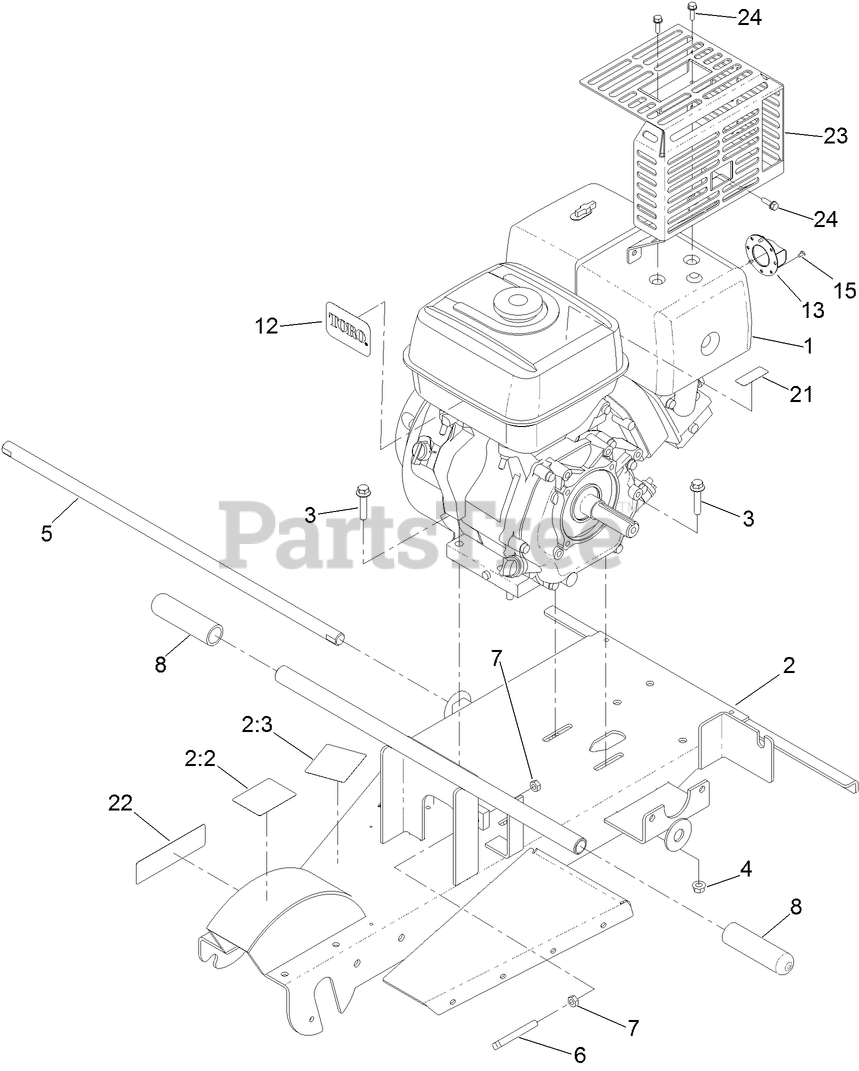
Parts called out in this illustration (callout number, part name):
2	FRAME ASM
2:2	DECAL-DANGER
2:3	DECAL-CAUTION
3	SCREW-HHF
4	NUT-HF
5	BAR-AXLE
6	SCREW-SET, SQH
7	NUT-HEX
8	GRIP-HANDLE
12	DECAL
13	DEFLECTOR-EXHAUST, HONDA
15	SCREW-SELF TAPPING
21	DECAL-WARNING, ETHANOL
22	DECAL-ROTATE TOOTH
23	GUARD-MUFFLER,
